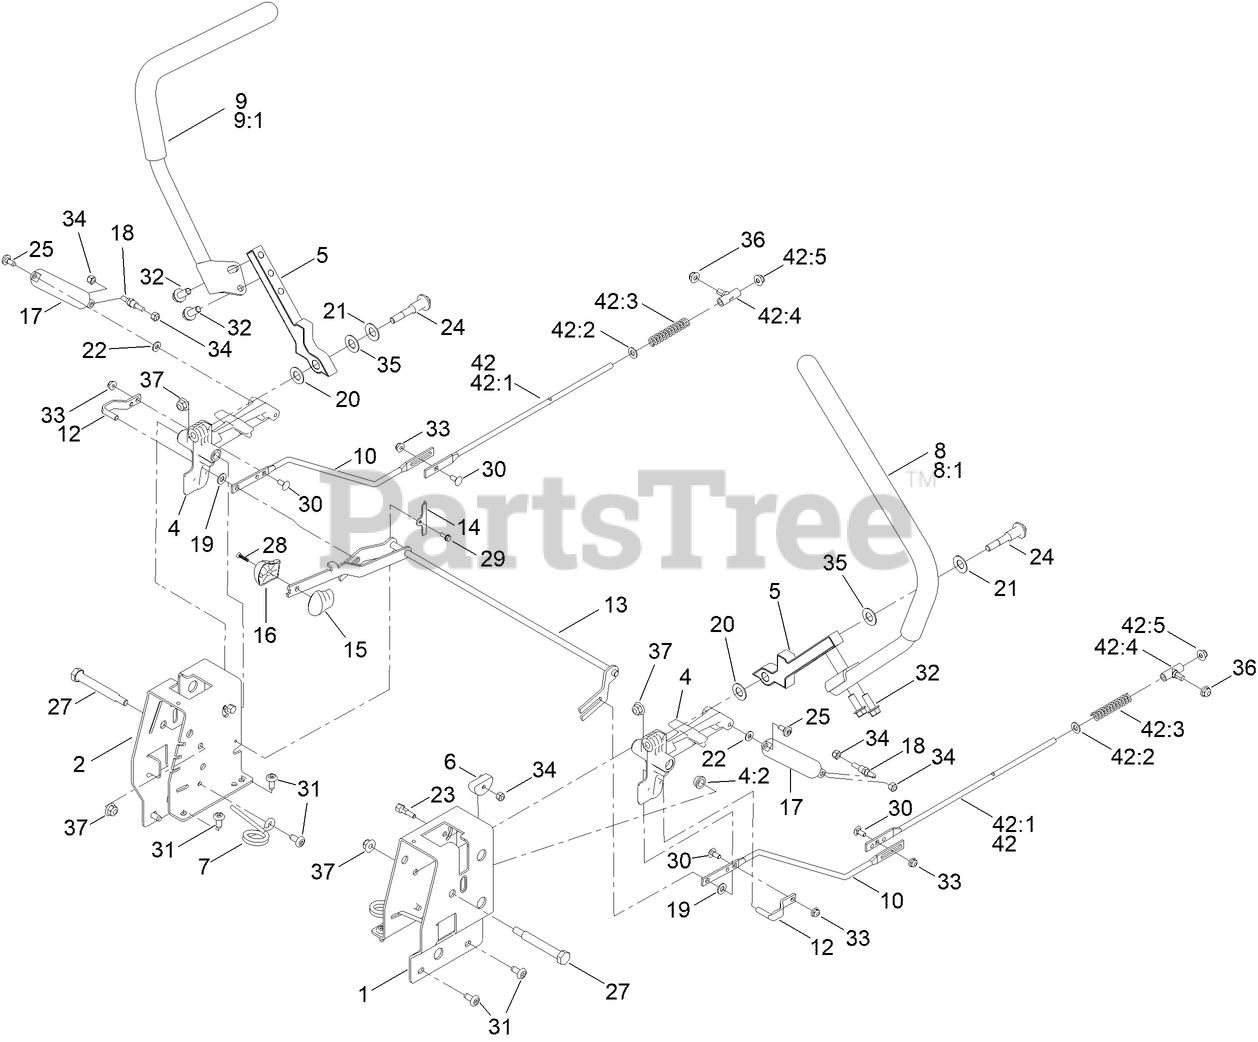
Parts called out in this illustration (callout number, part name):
1	PLATE-CONTROL BOX, LH
2	PLATE-CONTROL BOX, RH
4	ACTUATOR ARM ASM
4:2	BUSHING-FLANGE
5	ARM-CONTROL
6	ECCENTRIC
7	SPRING-TORSION
8	HANDLE-CONTROL, LH
9	HANDLE-CONTROL, RH
10	ROD-HYDRO, FRONT
12	PIN-ROD, HYDRO
13	SPEED CONTROL ASM
14	PLATE-RETAINER
15	KNOB-RH
16	KNOB-LH
17	DAMPER-NON CAVITATING
18	STUD-DAMPER
19	SPACER-NYLON
20	WASHER-NYLON
21	WASHER-BELLEVILLE
22	WASHER
23	BOLT-PIVOT, ECCENTRIC
24	BOLT-PIVOT
25	SCREW-SHOULDER
27	BOLT-PIVOT
28	SCREW-PPH
29	SCREW-TAPTITE
30	SCREW-CARR
32	SCREW-HHF
33	NUT-HF
34	NUT-LOCK, NI
35	WASHER
36	NUT-HF
37	NUT-HF, NI
42	ROD HYDRO ASM
42:1	ROD-HYDRO, REAR
42:2	WASHER-PLAIN
42:3	SPRING-COMPRESSION
42:4	MOUNT-ROD, HYDRO
42:5	NUT-HF
